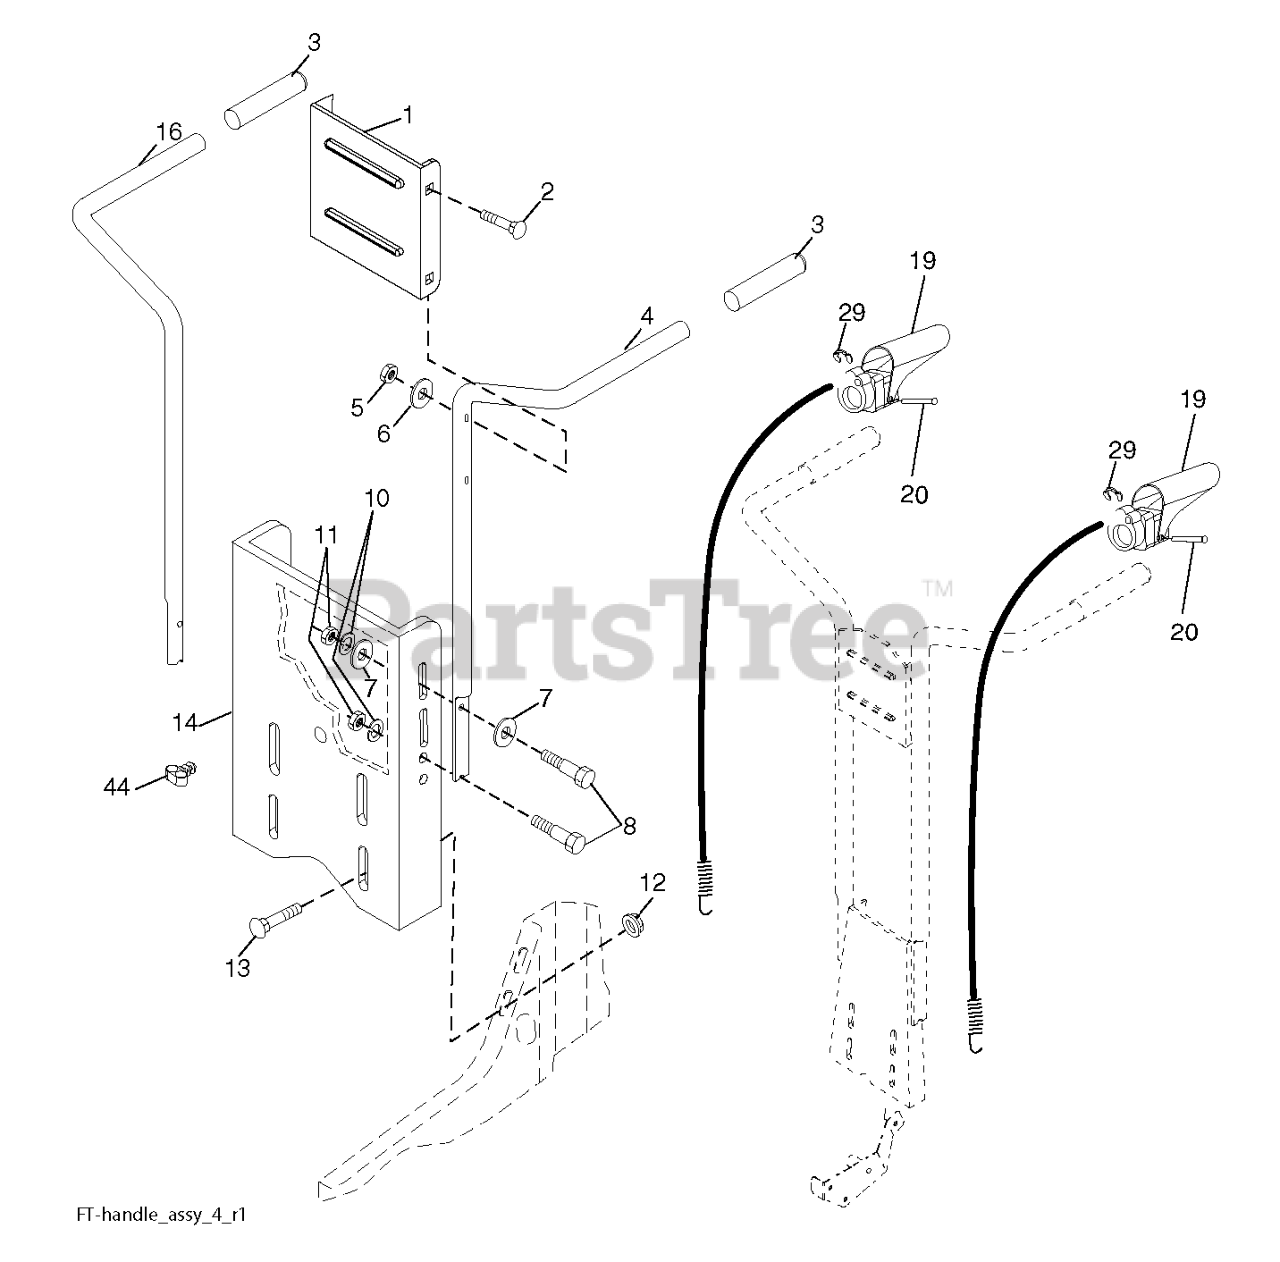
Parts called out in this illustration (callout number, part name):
2	BOLT
4	HANDLE.PNT.LH.DOUBLE.BEND
5	LOCKNUT
6	WASHER
7	WASHER.5/16.FLAT.STE.STD.
8	BOLT
10	WASHER.LOCK.HVY.HLCL.SPR.5/16
12	NUT
13	BOLT, RDHD SQNK 5/16-18 X 3/4
19	CONTROL ASM.TINE.49.88
20	PIN, PIVOT
29	RETAINING.RING.#5103-25
44	CLIP.ROUTING DUAL
